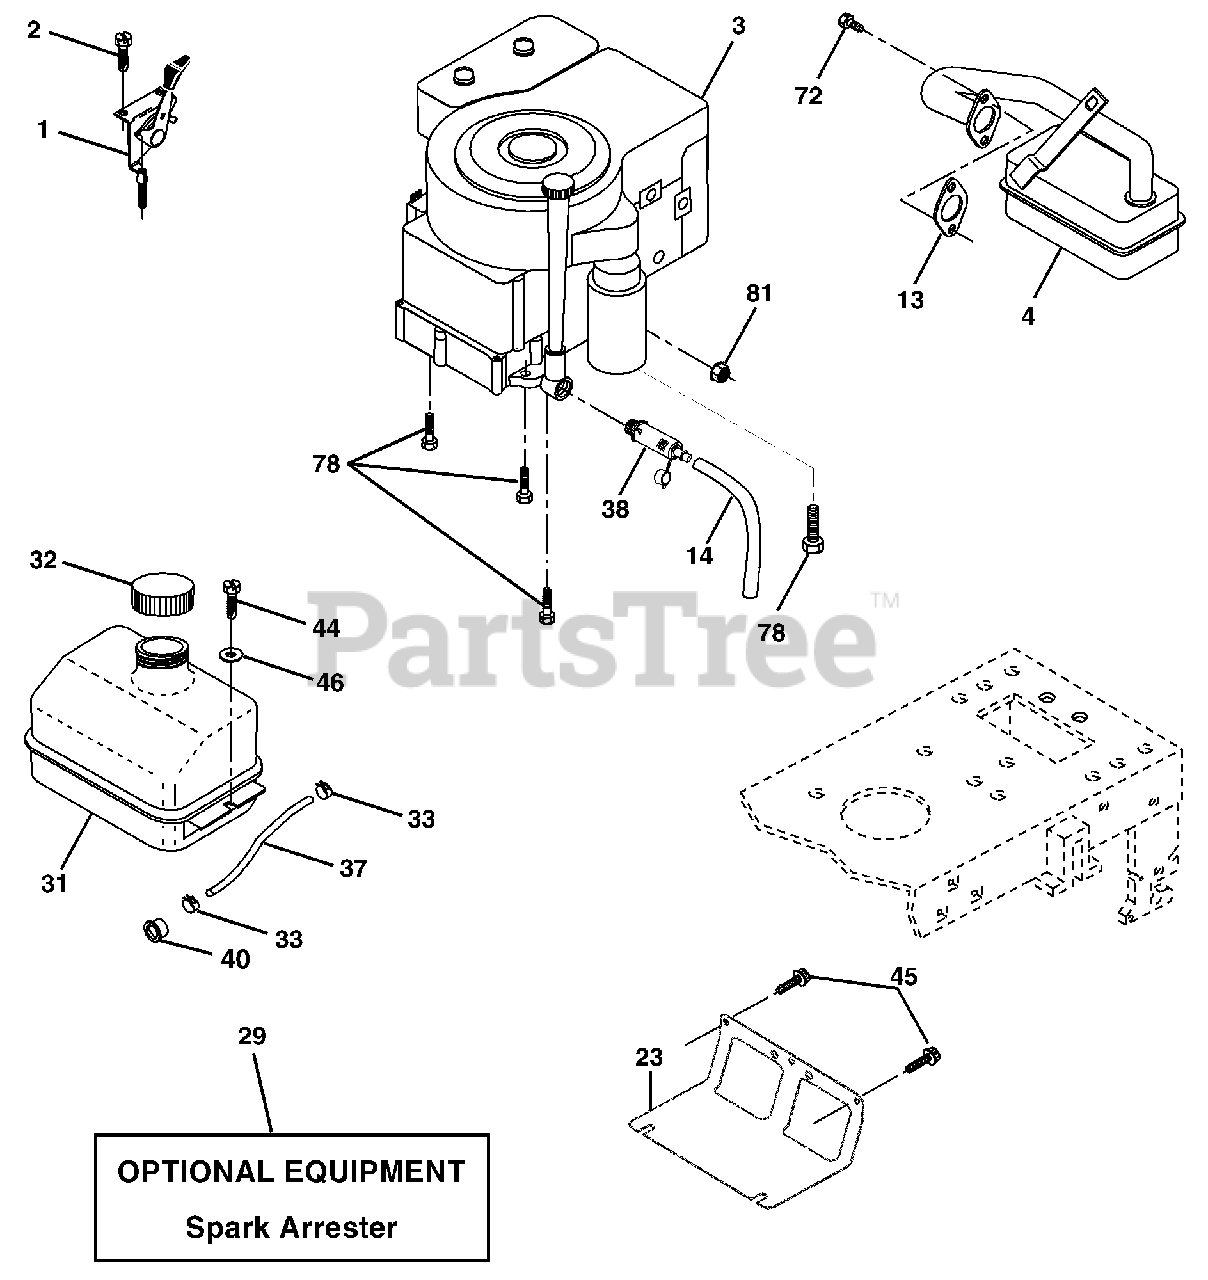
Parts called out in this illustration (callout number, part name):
1	Control, Throttle
2	Screw, Hex Head, Thread Cutting 1/4-20 x 1/2
4	Muffler
13	Gasket
14	Tube Drain Oil Easy
23	Shield Brn/Dbr Guard
29	Arrestor, Spark
31	Tank, Fuel
32	Cap Assembly, Fuel
33	Clamp, Hose
37	Line, Fuel
38	Plug Drain Oil Easy
40	Bushing, Snap, Fuel Line
44	Screw, Hex Washer Head, Thd., Roll. 1/4-20 x 3/4
45	Screw Hxwsh Thdr 3/8-16 x 3/4
46	Washer 9/32 x 7/8 x 16 Ga
72	Screw Socket Head 5/16-18 x 1
78	Screw 3/8-16 x 1-1/4
81	Nut Keps Hex 1/4-20 Unc
